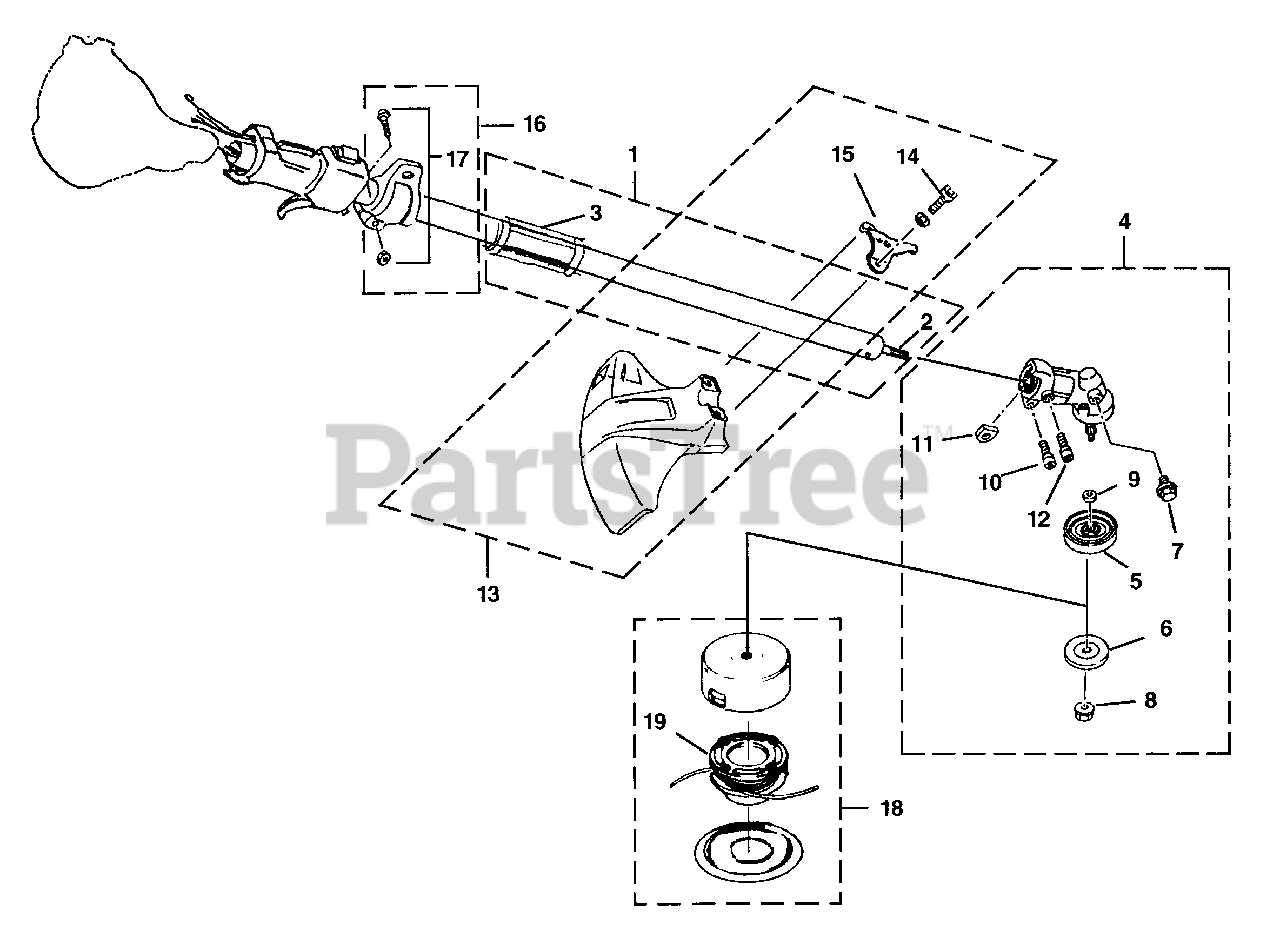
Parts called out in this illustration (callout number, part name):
1	DRIVESHAFT HOUSING
2	DRIVESHAFT
4	GEAR HEAD
5	WASHER-Flange
6	WASHER-Cupped
7	BOLT-Grease (M6 x 9)
10	BOLT ASSEMBLY (M5X 25 SW)
12	BOLT ASSEMBLY (M5 X 12 SW)
13	DEFLECTOR ASSEMBLY (Grass)
14	BOLT (M6 x 30)
16	HANGER ASSEMBLY
17	SCREW ASSEMBLY (M5 x 14)
18	STRINGHEAD ASSEMBLY (.080)
19	SPOOL & STRING (.080)
